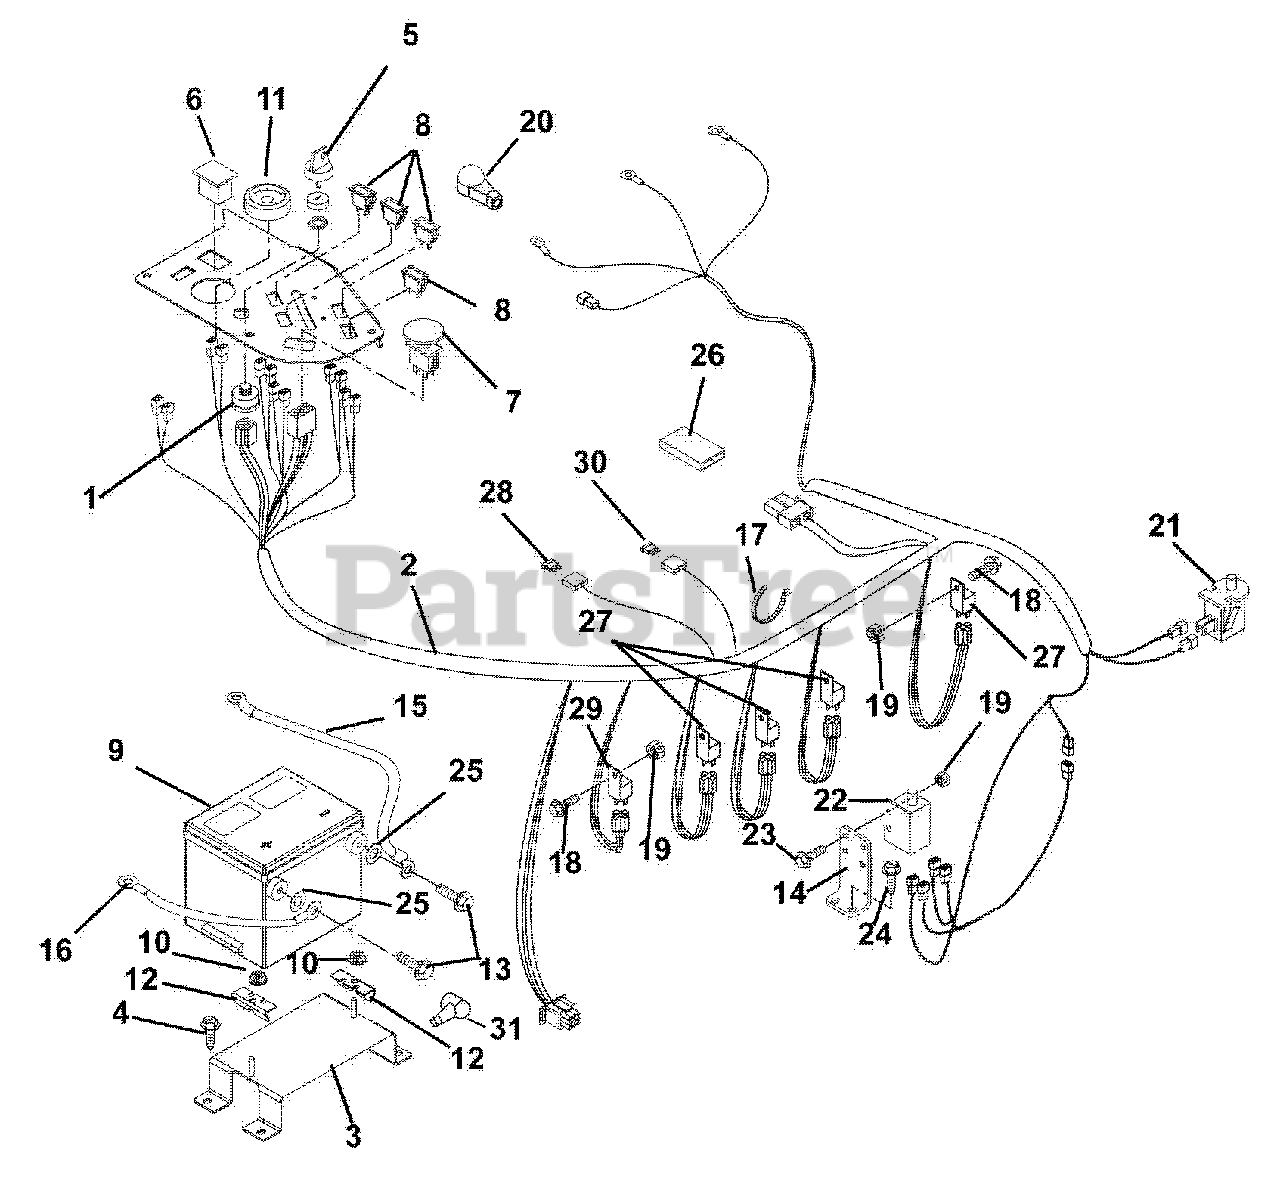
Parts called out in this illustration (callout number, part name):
1	Switch, Ignition
2	Harness, Wiring
3	Weldment, Battery Support
4	Screw-Tapping .38-16 x .75 Hex Washer Head
5	Key-with Cap
6	Hour Meter
7	Switch-Clutch With Retainer Ring
8	Light-Indicator
9	Battery with Tube
10	Nut-Locking-Top-Flange .31-18
11	Gauge, Temperature
12	Bracket, Battery Hold-Down
13	Bolt-Hex .25-20 x .75 Grade 5
14	Mount, Safety Switch
15	Cable, Positive Battery with Boots
16	Cable, Negative Battery
17	Cable Tie
18	Screw-Machine 10-24 x .75 Hex Washer Head
19	Nut-Locking-Nylon 10-24 With Insert
20	Boot Terminal, Red
21	Switch, Snap Mounting (N.O.) (Included with Seat)
22	Switch-Single Pole
23	Screw-Machine 10-24 x .75 Hex Washer Head
24	Screw-Tapping .25-20 x .50 Hex Washer Head
25	Washer-Flat-Steel .406 x 1.00 x ..083
26	Diode, Connector Shell
27	Relay (Included with Harness)
28	Fuse, ATO 30 Amp (Included with Harness)
29	Pre-Heat Timer (Included with Engine)
30	Fuse, ATO 60 Amp (Included with Harness)
31	Battery Terminal Boot, Red
